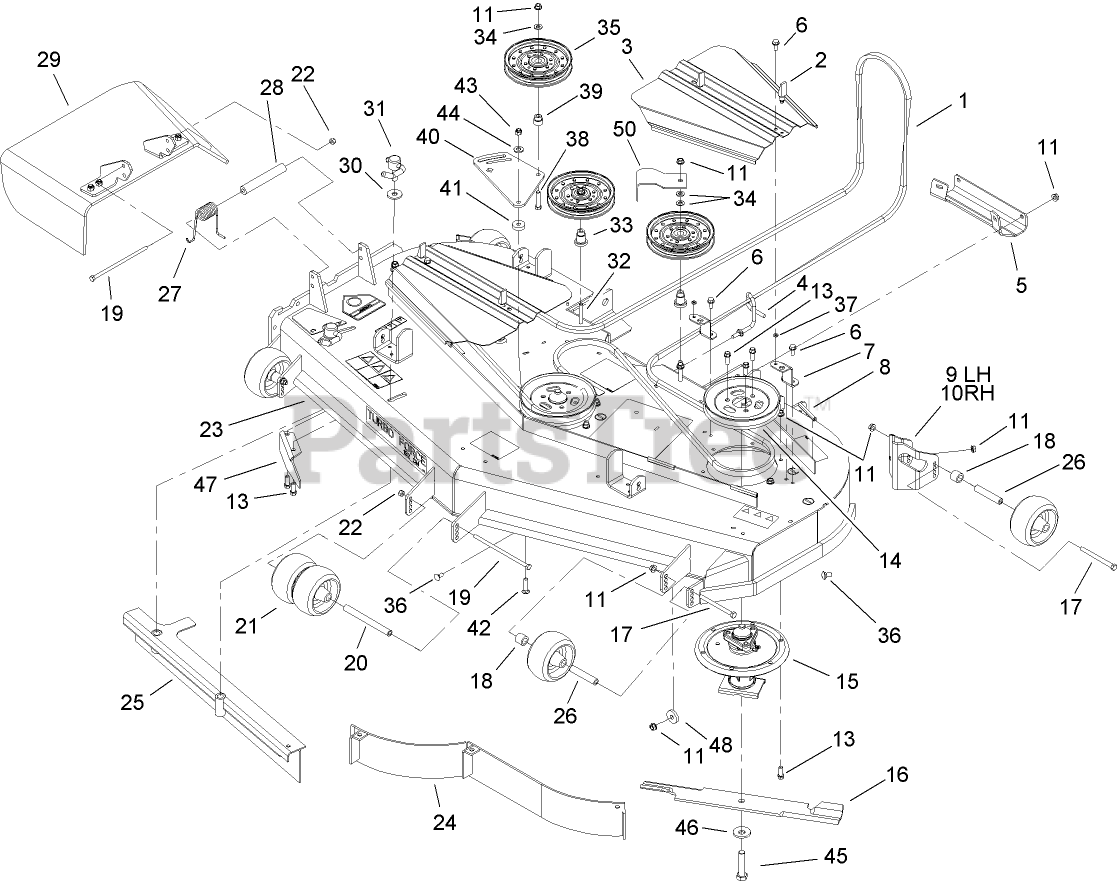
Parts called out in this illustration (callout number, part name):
2	LATCH-SWELL
3	Cover-Belt
4	GUIDE-BELT
5	Plate-Skid
6	SCREW-HWHTF
7	Bracket-Cover
8	STRIP-SEAL
9	MOUNT-WHEEL, LH
10	MOUNT-WHEEL, RH
11	NUT-HHF, WHIZ
13	SCREW-HWH
14	Pulley
15	Spindle ASM
16	BLADE-HI FLOW
17	SCREW-HH
18	TUBE-SPACER
19	SCREW-HH
20	SPACER-WHEEL
21	ROLLER-SCALP, ANTI
22	NUT-LOCK, NI
23	DECK ASM
26	TUBE-SPANNER
27	SPRING-TORSION
28	SPACER
29	RUBBER DEFLECTOR ASM
30	WASHER-PLASTIC
31	Lever ASM
32	SCREW-HH
33	MOUNT-PULLEY
34	WASHER-FLAT
35	Idler-Flat
36	SCREW-CARR
37	WASHER
38	SCREW-HH
39	BUSHING-IDLER
40	Plate-Idler
41	Spacer
42	SCREW-CARR
43	NUT-LOCK, NI
44	WASHER-BELLEVILLE
45	Screw-Cap
46	Washer-Blade Bolt, Heavy
47	BAFFLE-DISCHARGE
48	WASHER
50	GUIDE-BELT
